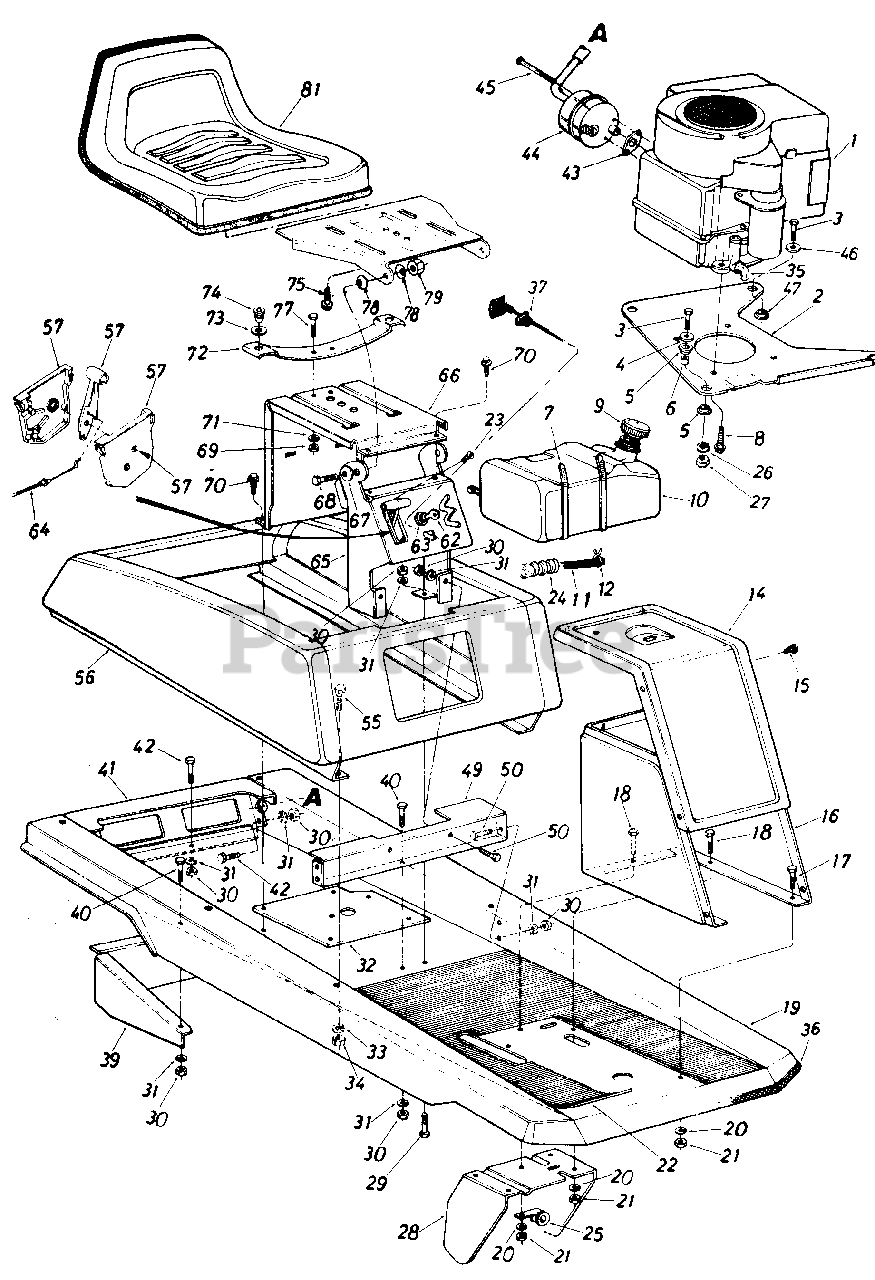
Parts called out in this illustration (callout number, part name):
1	Engine
2	Engine Mounting Plate
3	Hex Bolt 5/16-24 x 1.25" Lg.
4	Fl-Wash. .330" I.D. x 1.125"
5	Engine Mounting Grommet
6	Spacer .315" I.D. x .50" O.D. x.520" Lg.
7	Cable Tie 30.6 Lg.
8	Hex Wash. Hd. Self-Tap Scr. 3/8-16 x 1.25" Lg.
9	Gas Gauge
10	Fuel Tank
11	Gas Line
12	Hose Clamp .406" Dia.
22	Floor Mat
23	Truss Mach. AB-Tap Scr. #10 x .50" Lg.
24	Convoluted Conduit
25	Clamp
26	L-Wash. 5/16" I.D.
27	Hex Nut 5/16-24 Thd.
28	Clutch-Brake Pedal Ass'y.
29	Hex Bolt 5/16-18 x .75" Lg
30	Hex Nut 5/16-18 Thd.
31	L-Wash. 5/16" I.D.
32	Mounting Brkt. Variable Speed Pulley
33	L-Wash. 1/4" I.D.
34	Hex Nut 1/4-20 Thd.
35	90ø Elbow Male To Female
36	Trim Strip 18" Lg:
37	Choke Control
39	Transaxle Support Ass'y.
40	Hex Bolt 5/16-18 x .75" Lg.
43	Exhaust Gasket
44	Muffler Ass'y.
45	Shld. Bolt
46	Fl-Wash. .330" I.D. x 1.25" O.D.
47	Flange Wash. .320" I.D. x .750" O.D.
49	Seat Support & Frame Brkt.
50	Hex Bolt 5/16-18 x .75" Lg.
55	Hex Bolt 1/4-20 x .50" Lg.
57	Throttle Control Box Ass'y.
62	Ignition Key
63	Ignition Switch
64	Throttle Control Wire
65	Front Seat Bracket
66	Rear Seat Bracket
67	Bell-Wash. .345" I.D. x .88"
68	Hex Bolt 5/16-18 x .75" Lg.
69	Hex Nut 5/16-18 Thd.
70	Hex Self-Tap Scr. 5/16-18 x .75" Lg.
71	L-Wash. 1/4" I.D.
72	Seat Spring
73	Fl-Wash. .531" I.D. x .930"
74	Grommet
75	Hex Wash. Hd. Tap Scr. 3/8-16 x 3/4" Lg.
77	Hex Bolt 1/4-20 x .75" Lg.
78	Bell-Wash. .345" I.D. x .88"
79	Hex Cent. L-Nut 5/16-18 Thd.
81	Seat Ass'y. Comp.
